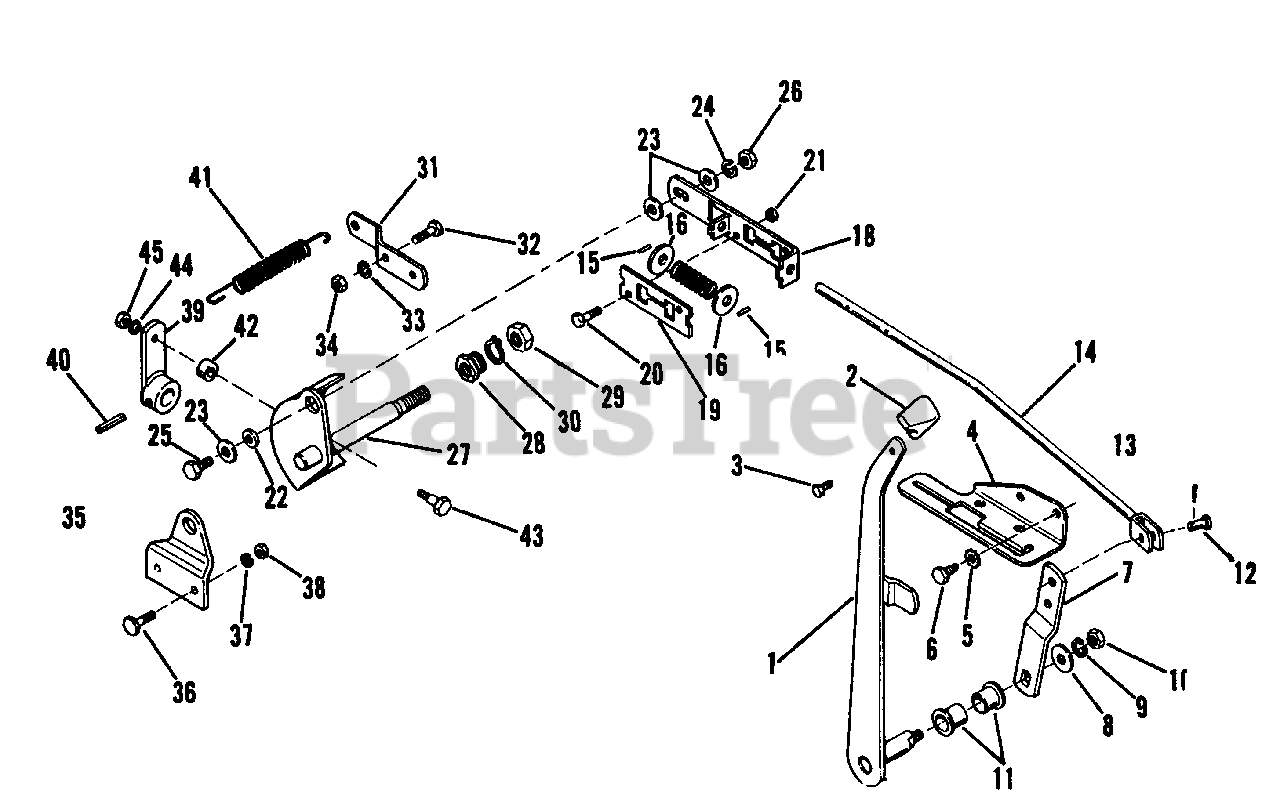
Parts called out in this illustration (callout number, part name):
1	LEVER ASSEMBLY, Control
3	SCREW, Thread Forming 1/4"-20 x 3/4" lg.
4	QUANDRANT
5	LOCKWASHER Shakeproof, 5/16"
6	SCREW, Special
8	WASHER, Plain, 3/8"
9	LOCKWASHER, 3/8"
10	NUT, Hex, Full, 3/8"-16
13	PIN, Cotter 3/32" x 3/4" lg.
14	ROD ASSEMBLY, Control
16	WASHER, Plain, 3/8"
18	GUIDE, Control Rod
19	PLATE, Guide
20	CAPSCREW, Hex, 1/4"-20 x 1-1/4" lg.
21	NUT, Hex, Full, Lock, 1/2"-20
23	WASHER, Plain, 5/16"
24	LOCKWASHER, 3/8"
25	CAPSCREW, Hex, 3/8"-16 x 1" lg.
26	NUT, Hex, Full, 3/8"-16
27	SHAFT ASSEMBLY
28	NUT, Adjusting
29	NUT, Hex, Jam, 1/2"-13
30	RING, Retaining
31	SUPPORT, Spring
32	CAPSCREW, Hex, 5/16"-18 x 1" lg.
33	LOCKWASHER, 5/16"
34	NUT, Hex, Full, 5/16"-18
35	BRACKET, Pivot
36	SCREW, Hex
37	LOCKWASHER, 5/16"
38	NUT, Hex, Full, 5/16"-18
39	LINK ASSEMBLY, Control
40	PIN, Roll, 1/4" x 1-1/4" lg.
42	ROLLER, Cam
43	BOLT, Shoulder
44	LOCKWASHER, 1/4"
45	NUT, Hex, Full, 1/4"-20
